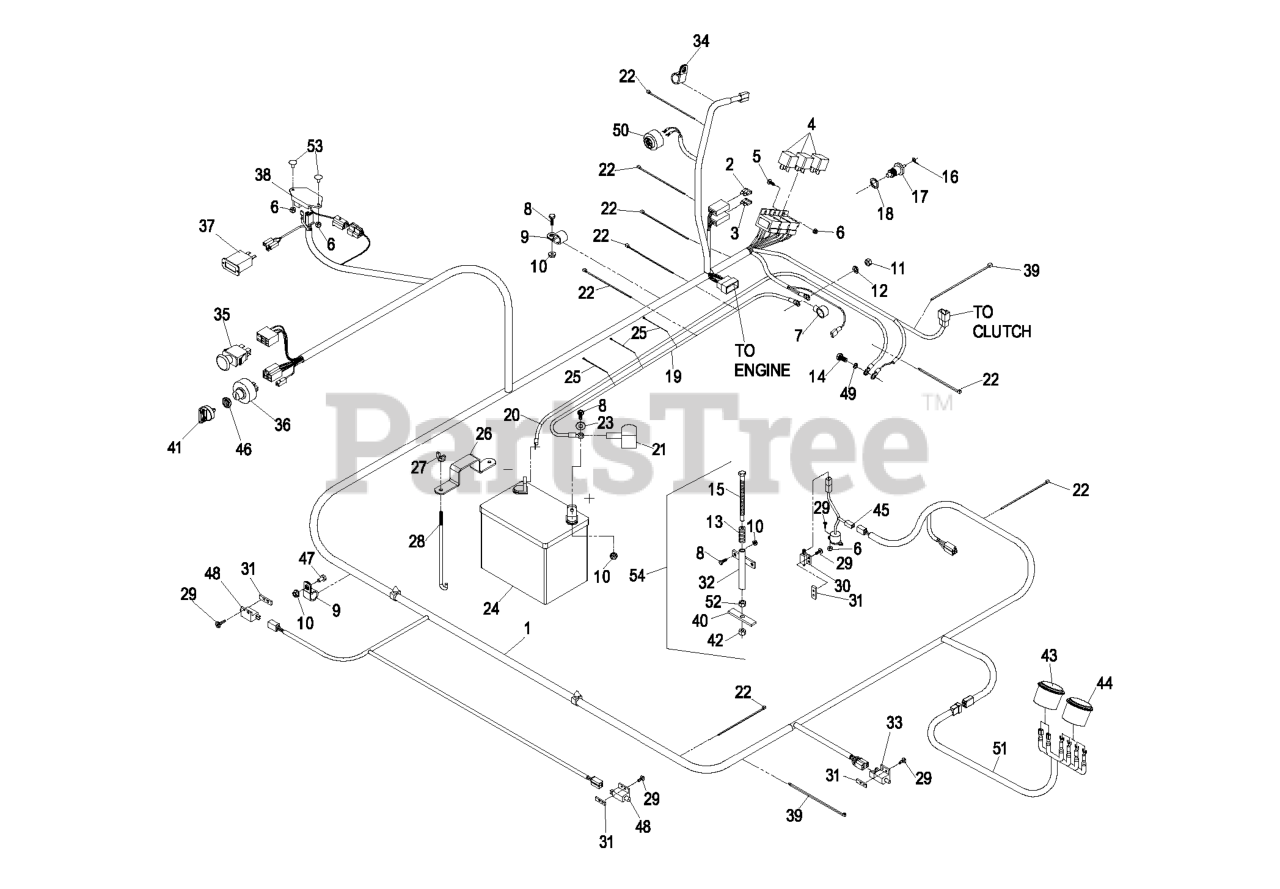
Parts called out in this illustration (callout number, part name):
1	HARNESS,WIRE LZ 27LKA
2	FUSE-BLADE TYPE, 20 AMP
3	FUSE-BLADE TYPE, 30 AMP
6	NUT-LOCK, NI
7	INSULATOR-SOLENOID
8	SCREW-HH
9	CLIP-LOOM
11	NUT-HEX
12	WASHER-PLAIN
13	SPRING-SWITCH, SEAT
14	SCREW-HH
15	SCREW-HH
17	SENDER-TEMPERATURE
18	WASHER-ALUMINUM
20	WIRE-GROUND
22	TIE-PLASTIC
23	WASHER-FLAT
25	TIE-CABLE
26	STRAP-HOLDDOWN
27	WINGNUT
28	BOLT-HOLDDOWN
29	SCREW-PPH
30	SWITCH-CLOSED, NORMALLY
31	PLATE-TAPPED
32	MOUNT-SPRING, SEAT
34	CLIP-LOOM
35	SWITCH-PTO
37	METER-HOUR
38	MODULE-DELAY, SEAT
39	TIE-PLASTIC
40	PLATE-SWITCH, SEAT
41	KEY-IGNITION
42	NUT-LOCK, NI
43	GAUGE-VOLTMETER
44	GAUGE,TEMP W/ ALERT
46	NUT-SWITCH, IGNITION
47	SCREW-HH
48	SWITCH-OPEN, NORMALLY
49	WASHER-PLAIN
50	ALARM-TONE, DUAL
51	HARNESS,GAUGE 27 LKA
52	NUT-HEX
53	BOLT-CARR
54	ASM,SEAT SWITCH ACTUATOR
